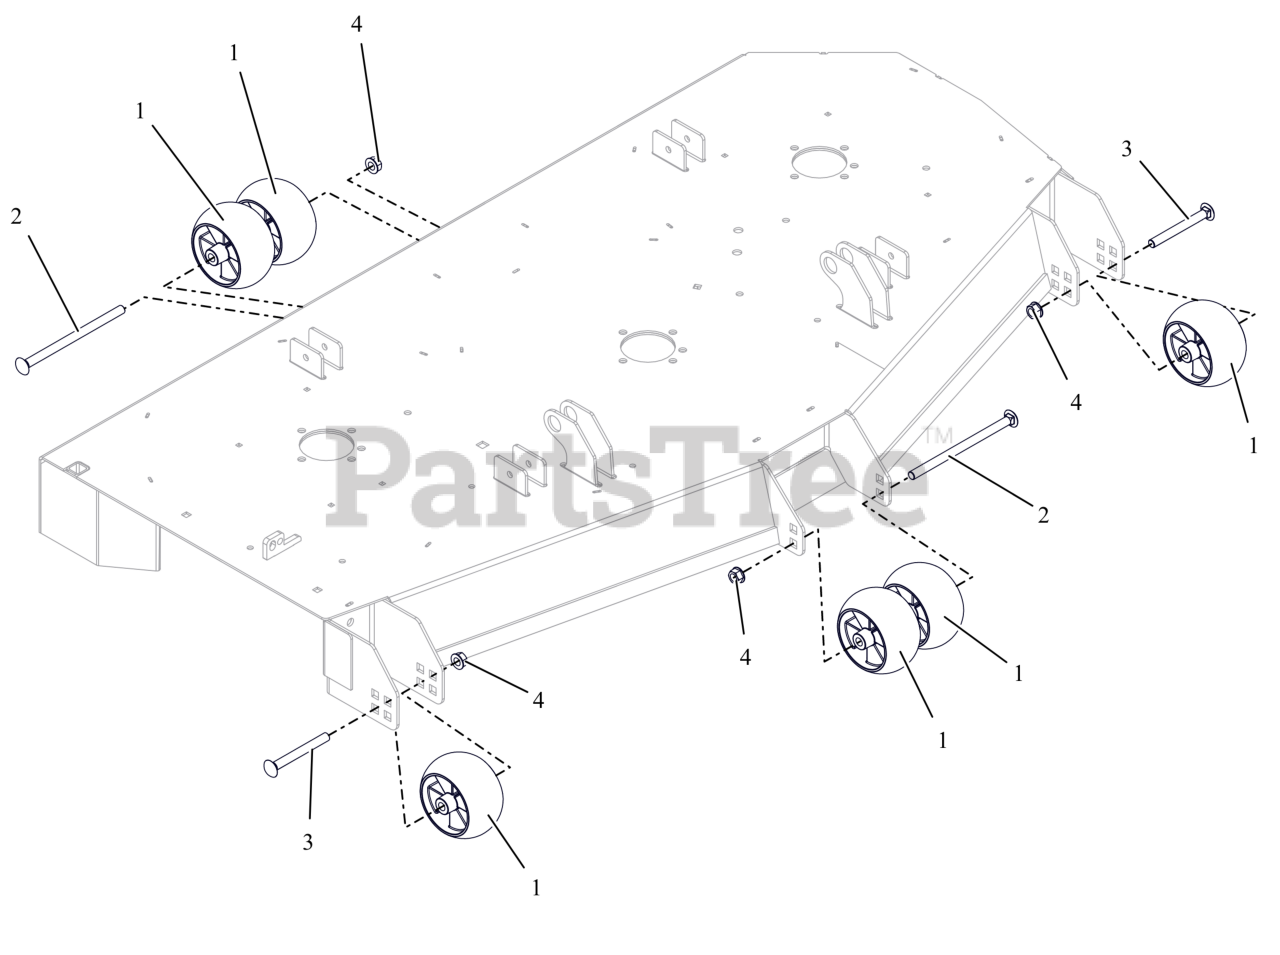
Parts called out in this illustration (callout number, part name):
1	WHEEL, ANTI SCALP - 5X3 CTR W/RIBS
2	BLT,RHSN .50-13X8.00 G5 ZCC NS
3	BLT,RHNS .50-13X4.50 G5 ZCC NS
4	NUT-LK-CTR-FLG .500-13 GG ZCC
